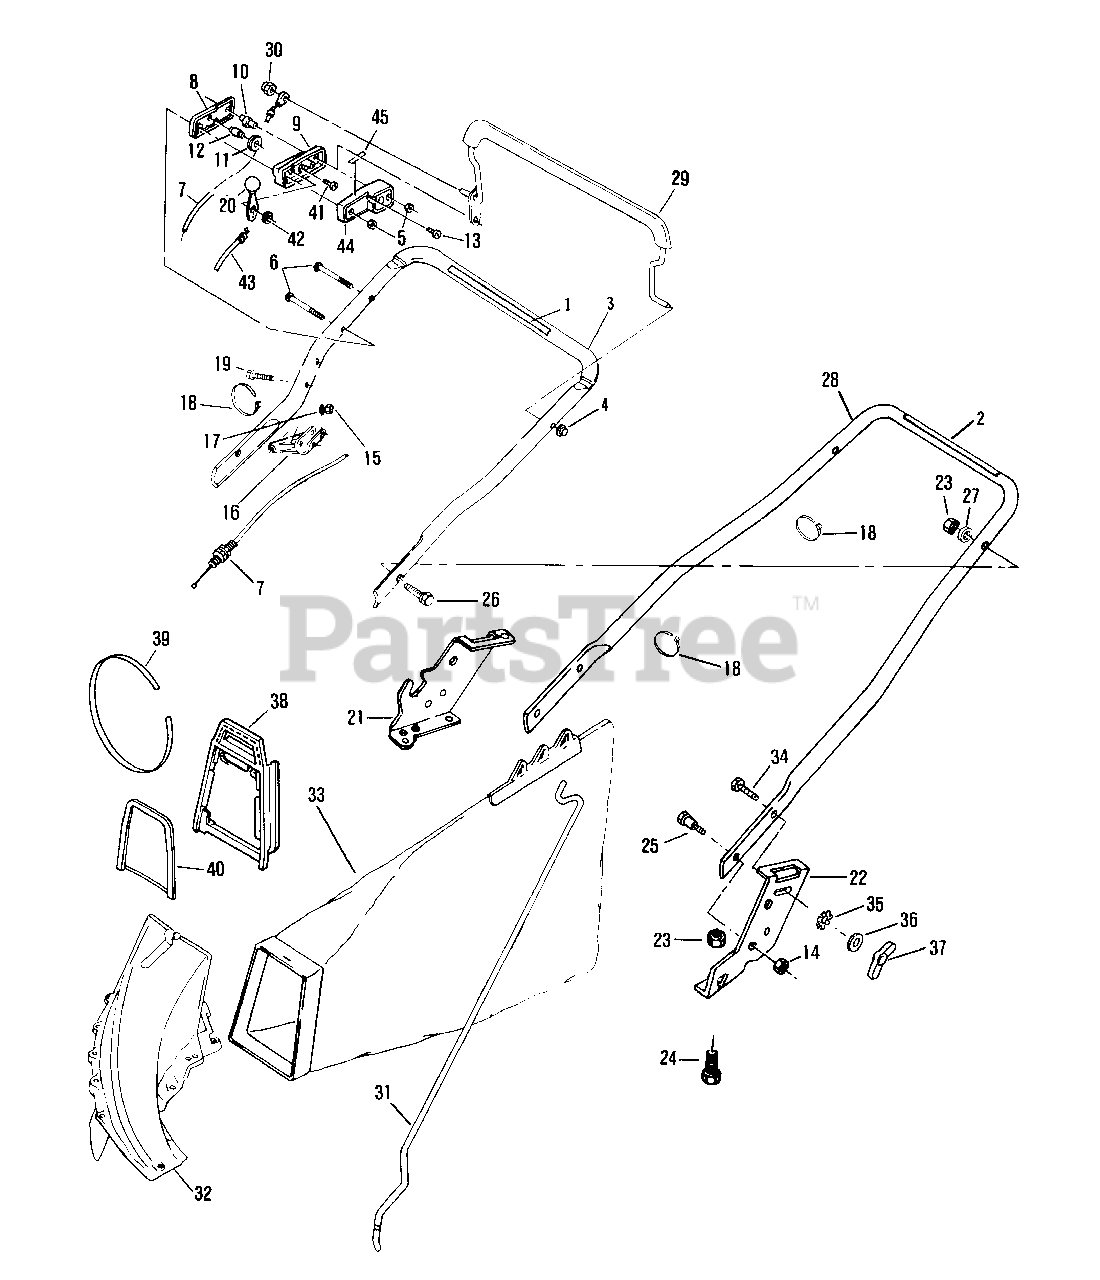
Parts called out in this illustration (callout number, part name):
1	Decal-Engine/Blade Control
2	Decal-Starting Instructions
3	Top Handle
4	Pushnut
5	Nut-Hex-Centerlock
6	Screw
7	Control Cable Assembly
8	Control Case-Outer
9	Case-Throttle Control
10	Column
11	Pulley
12	Pin
13	Screw
14	Nut-Handle to Handle Bracket
15	Locknut
16	Rope Guide Assembly
17	Washer
18	Tie Strap
19	Screw-Truss Head
20	Lever/Knob
21	Handle Bracket-R.H.
22	Handle Bracket-L.H.
23	Nut-Handle Bracket and Handle
24	Bolt-Handle Bracket to Housing
25	Bolt-Handle to Handle Bracket
26	Screw-Handle
27	Washer
28	Handle-Bottom
29	Control Lever and Nut Assembly
30	Nut-Acorn
31	Grass Bag Rod
32	Chute Assembly
33	Grass Bag
34	Screw
35	Lockwasher
36	Washer
37	Wing Nut
38	Adapter-Chute
39	Strap
40	Brace-Chute
41	Screw
42	Washer-Spring
43	Cable-Throttle
44	Case-Throttle,Inner
45	Decal-Throttle Control
